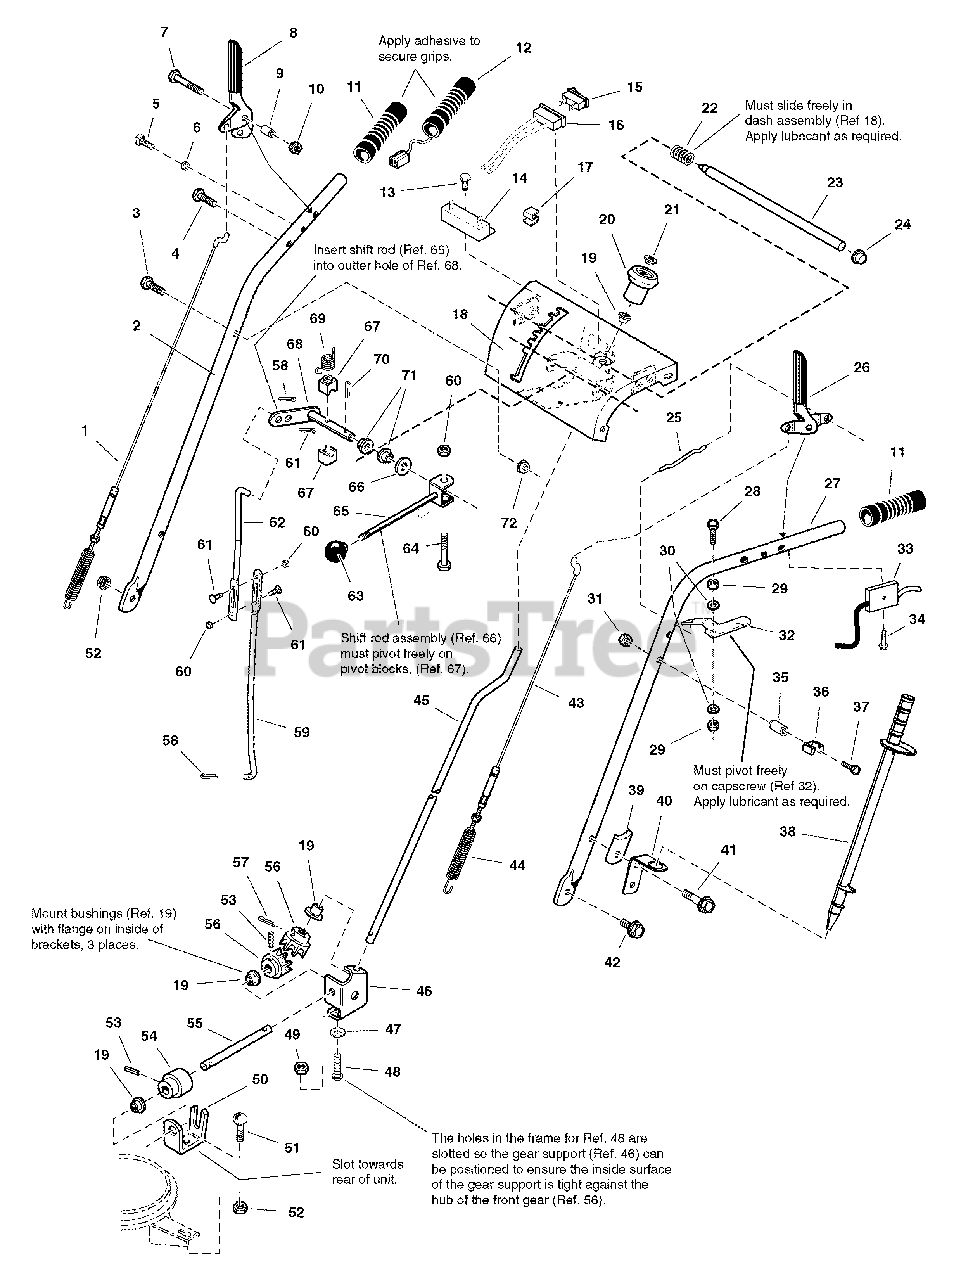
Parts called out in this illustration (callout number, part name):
1	CABLE AND SPRING ASSEMBLY, R.H. Auger
2	HANDLE, Tube, R.H.
3	SCREW, Hex Head Cap, 5/16-18 x 1 3/4
4	CAPSCREW, Hex Head, 5/16-18 x 1-1/2 G5
5	SCREW, Pan Head Torx, 1/4-20 x 3/4, Thread Cutting
6	SPACER, 1/4ID x 25/64OD x 11/64LG
7	CAPSCREW, Hex Head, 1/4-20 x 1-1/2 G5
8	HANDLE, Clutch R.H.
10	NUT, Hex Centerlock, 1/4-20
12	HAND GRIP, Heated 1" Diameter
13	CAPSCREW, Hex Head 1/4-20 x 3/4 G5
14	RESISTOR BLOCK, 2 Male Terminal
15	SWITCH, Hand Warmer
16	HARNESS, Wiring
17	CLIP, Wire
18	DASH AND SUPPORT ASSEMBLY, Tubular
19	BUSHING, 47/125ID x 437/1000OD x 1/5LG
20	KNOB, Spinner
21	NUT, Push Pal, 3/8" Diameter Stud Capped
22	SPRING, Complete
23	ROD AND SPRING ASSEMBLY, w/Pin (Includes Ref. No. 24)
24	PUSH NUT, Stud Cap, 1/2
25	ROD, 4/25" Diameter, E-Coat
26	HANDLE, Clutch L.H.
27	HANDLE, Tube, L.H.
28	CAPSCREW, Hex Head, 1/4-20 x 2 G5
29	NUT, Hex Lock ESNA Light, 1/4-20NC-3B
30	WASHER, 1/4
31	NUT, Hex Lock, 10-24
32	LEVER, Pivot
33	CABLE AND HANDLE ASSEMBLY, Clutch
34	SCREW, Pan Head Torx, #10 x 1/2 Thread Cut
35	SPACER, 1-1/4 LG Beveled End
36	CLIP, Snow Stick
37	SCREW, Hex Flange Slot, #10-24 x 2-1/2
38	STICK, Snow Removal
39	CLAMP, Saddle Snow Handle E-Coat
40	BRACKET, Clean Out Tool
41	CAPSCREW, Hex Head Serrated Flange Taptite, 5/16-18 x 2 G5
42	CAPSCREW, Hex Whiz Lock Flange, 5/16-18 x 1
43	CABLE AND SPRING ASSEMBLY, L.H. Traction (Includes Ref. No. 44)
44	SPRING, Extension
45	ROD, 3/8" Diameter, 26"LG, E-Coat
46	SUPPORT, Gear
47	NUT, Push for 1/4 Diameter Thread
48	BOLT, Carriage, 1/4-20 x 5/8
49	NUT, Hex Flange, 1/4-20, Whiz Lock Small
50	SUPPORT, Worm
51	CARRIAGE BOLT, 5/16-18 x 3/4 G5
52	NUT, Hex Keps, 5/16-18, Conical Washer
53	PIN, Spring 1/8 x 3/4
54	WORM, Chute, L.H.
55	ROD, 3/8" Diameter, Chute Worm E-Coat
56	GEAR, Powdered Metal, Metafusion
57	PIN, Cotter 1/4 x 1
58	PIN, Quick
59	ROD, 3/4" Diameter
60	NUT, Hex KEPS, 1/4-20, Conical Washer
61	CARRIAGE BOLT, 1/4-20 x 3/4 G5
62	ROD, 3/4" Diameter, Shift Upper E-Coat, 11-19/50LG
63	KNOB, Intermediate Thread, 3/8-16
64	SCREW, Hex Whiz Lock Flange, 1/4-20 x 2-1/4
65	ROD AND CLEVIS ASSEMBLY, Shift, Threaded
66	WASHER, 1/2
67	BLOCK, Pivot, 3/4 x 3/4, Powdered Metal
68	ROD AND ARM ASSEMBLY, Pivot
69	SPRING, Torsion
70	CLIP, Hair Pin
71	BUSHING, 1/2ID x 3/4OD x 1/4LG
72	NUT, Hex Flange, 5/16-18 ESNA
